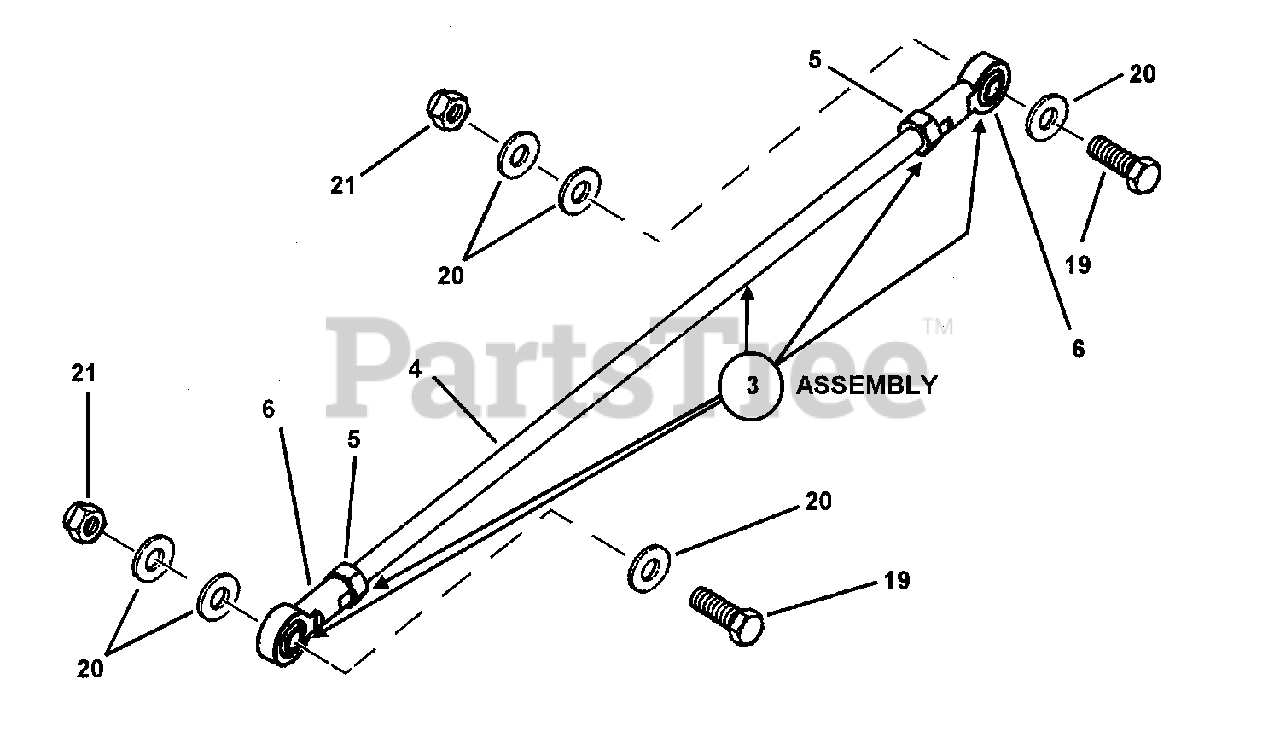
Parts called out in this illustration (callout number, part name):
3	ASSY, Pump Control Linkage (Incl. indented items below)
4	LINKAGE ROD, Pump Control (5/16-24 thread- both ends)
5	NUT, 5/16-24 Hex GR5 (2 per assembly)
6	LINKAGE, Ball Joint 5/16-24 (2 per assembly)
19	BOLT, 5/16-18 X 1-1/4 GD5 YZ
20	WASHER, 5/16" Flat
21	NUT, 5/16-18 HEX NYLON LOCK
